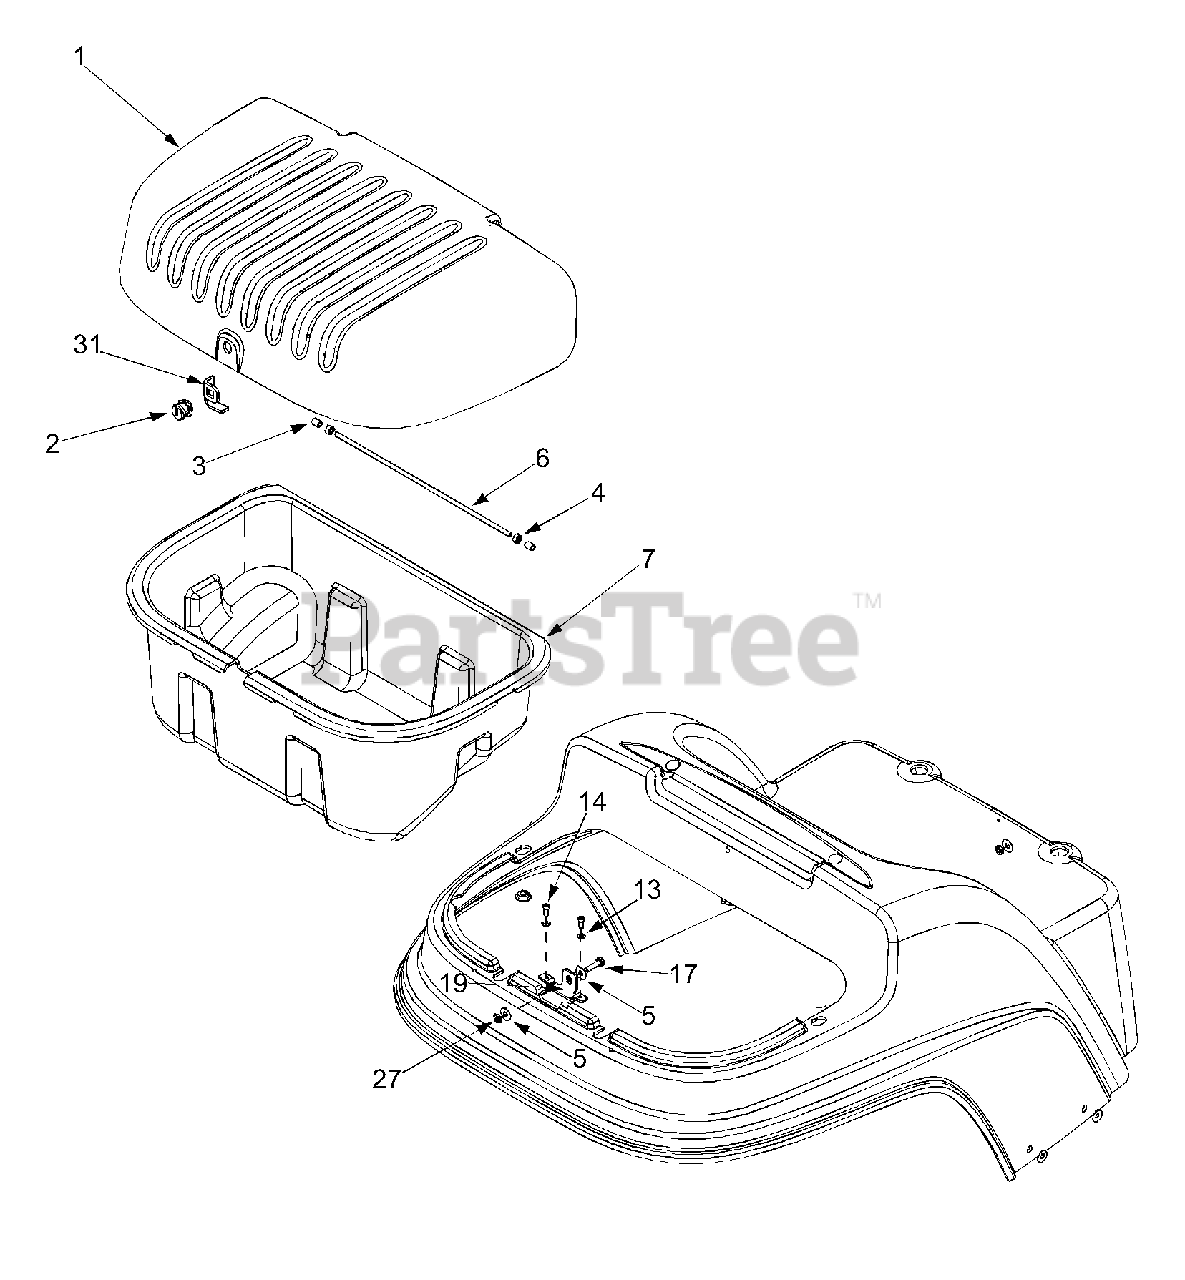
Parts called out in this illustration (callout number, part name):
1	Trunk Lid - Silver
2	Trunk Key Lock
3	Sleeve Bearing
4	Shaft Collar
5	Flat Washer .260 ID x .720 OD
6	Trunk Hinge Rod
7	Trunk Basket Panel
13	Flat Washer .203 ID x .403 OD
14	Screw 10-32 x .5
17	Cap Screw 1/4-20 x 1.0
19	Trunk Mounting Plate
27	Jam Nut 1/4-20
31	Trunk Lock
